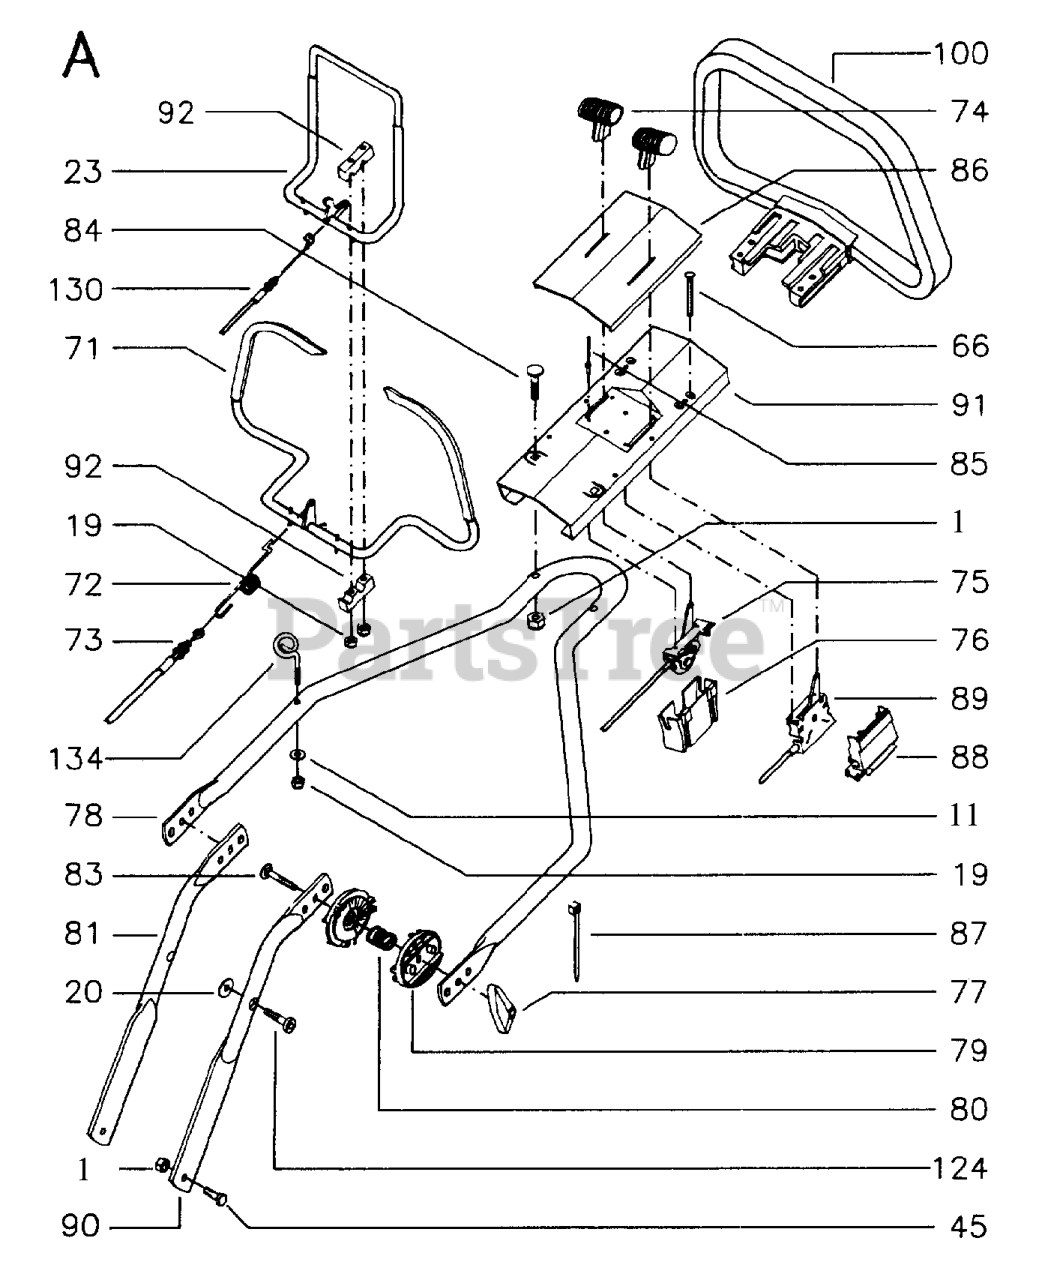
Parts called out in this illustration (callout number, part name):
2	CLUTCH ARM
9	PRESSURE SPRING
14	LOCKNUT M8
16	INDEXPLATE
17	WASHER - 15X7.3X1.6
20	LOCKNUT M6
23	BOLT FLANGE
